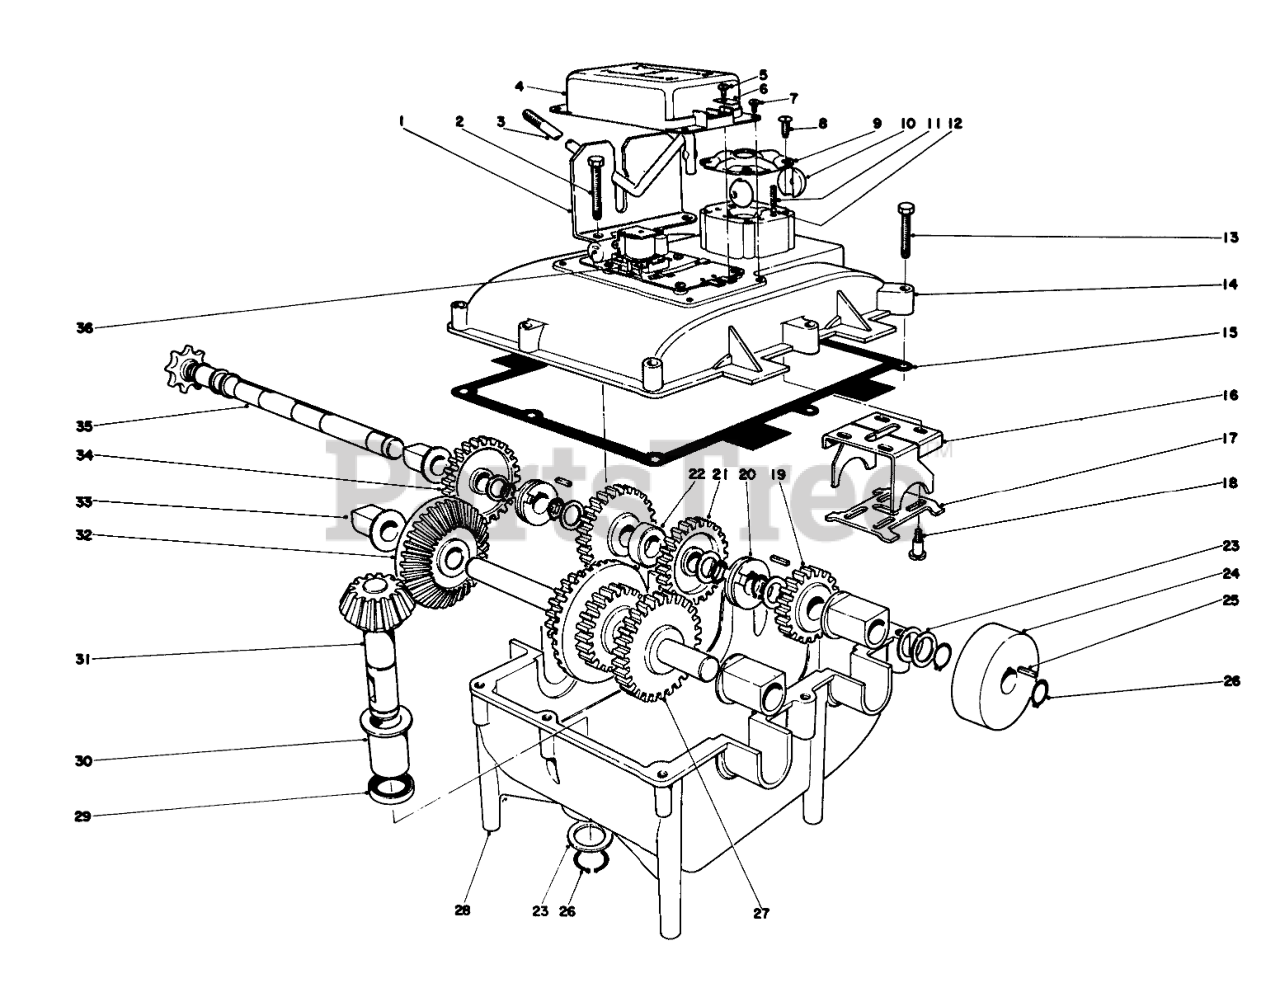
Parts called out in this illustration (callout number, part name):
1	Bracket Shift
3	Shift Rod
4	Housing Ign.-interlock
6	Terminal
9	Cap Shift
10	Ball Shift Segment
11	Spring
12	Ball-Detent
14	Cover-Gear Housing
15	Gasket
16	Yoke Shift
17	Plate-Backing
18	Screw Shoulder
19	Gear-24 Teeth
20	Dog Driving
21	Gear-30 Teeth
22	Spacer
23	Flat Washer
24	Brake Drum
26	RING-SNAP, EXTERNAL
27	Assembly-Drive Shaft
28	Housing Gear
29	Grease Seal
30	Bushing
31	Assembly-Pinion Shaft
32	Bevel Gear
33	Bearing
34	Gear 36 Tooth
35	Shaft Sprocket
36	Assembly Ignition Interlock
